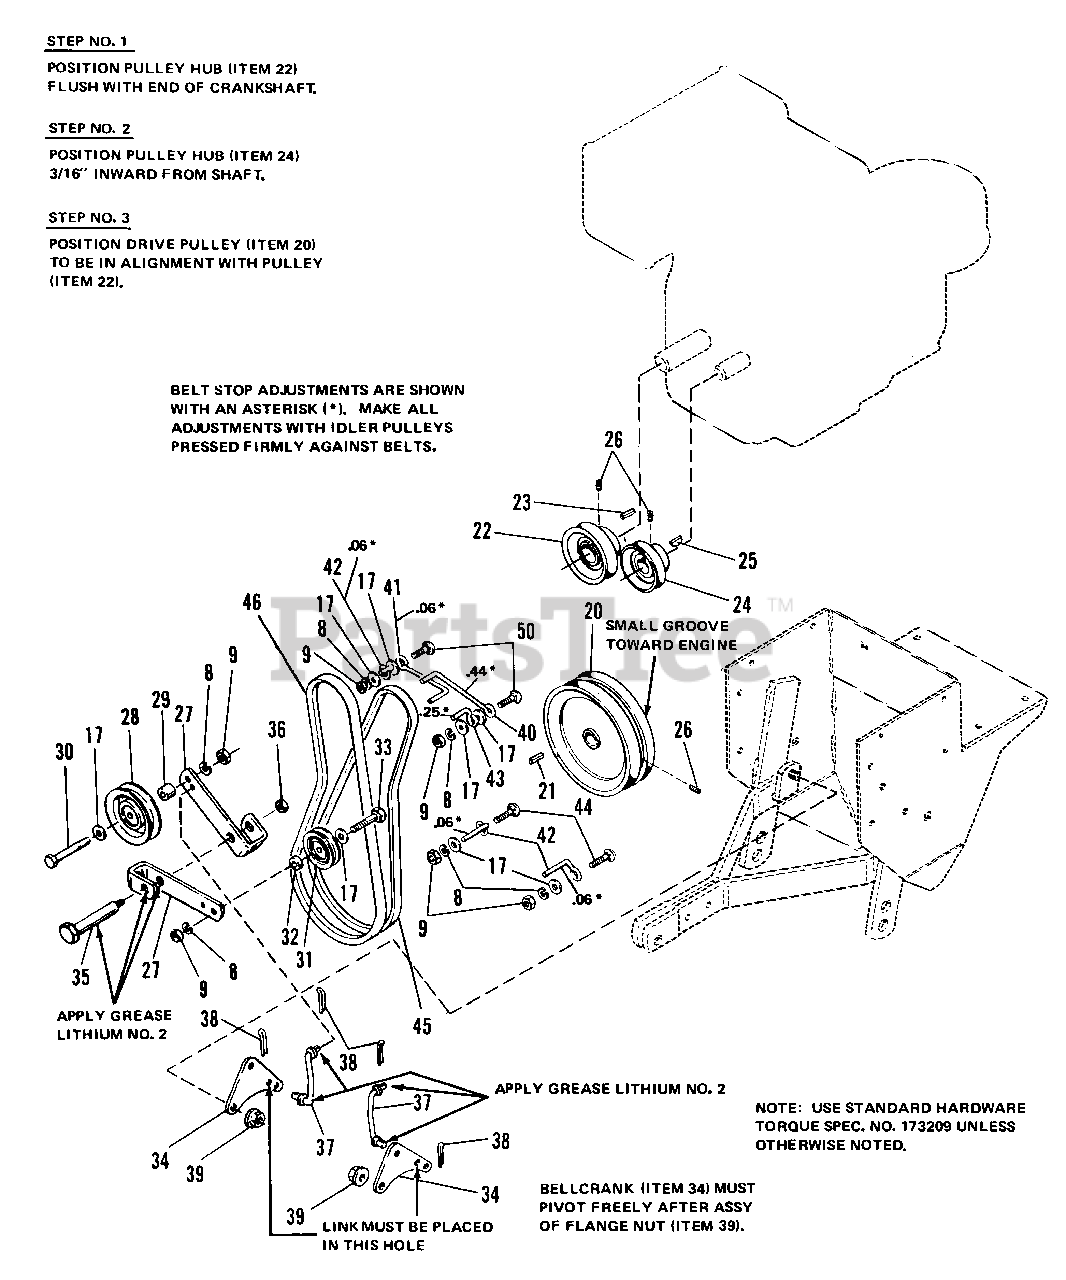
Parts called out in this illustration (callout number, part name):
1	FRAME ASSY
2	WHEEL & TIRE ASSY
3	BOLT, Shoulder
4	LOCKWASHER, Spring, 1/2
5	NUT, Hex, 1/2-13
6	STOP, Plate
7	CAPSCREW, Hex Hd., 3/8-16 x 1-1/2
8	LOCKWASHER, Spring, 3/8
9	NUT, Hex, Full, 3/8-16
10	BAR, Depth
13	PIN, Quick, 1-/78
15	CAPSCREW, Hex Hd., 5/16-18 x 1-3/4
16	WASHER, Plain, 3/8
17	WASHER, Plain, 5/16
18	LOCKWASHER, Spring, 5/16
19	NUT, Hex, 5/16-18
20	PULLEY, Drive
22	PULLEY, Forward
24	PULLEY, Engine, Reverse
25	KEY, Woodruff, #6, 5/32 x 5/8
26	SETSCREW, Hex Skt., Cup Pt., 5/16-18 x 5/16
27	LEVER, Idler Pulley
28	PULLEY, Idler
30	CAPSCREW, Hex Hd., 3/8-16 x 1-3/4
31	PULLEY, Idler
33	CAPSCREW, Hex Hd., 3/8-16 x 1-1/2
34	BELLCRANK
35	BOLT, Pivot
36	NUT, Hex, Full Lock, 5/16-18
37	ROD, Link
38	PIN, Cotter, 1/16 x 3/4
39	NUT, Hex Lock, Flange, 5/16-18
40	STOP, Belt
42	STOP, Belt
43	STOP, Belt
44	BOLT, Rd. Hd., Sq. Nk., 3/8-16 x 1
45	BELT, V (Reverse)
46	BELT, V (Forward)
48	SCREW, Hex, Wshr Hd., Taptite, 1/4-20 x 3/8
50	BOLT, Rd. Hd., Sq. Nk., 3/8-16 x 1-1/4
51	DECAL, 1008
52	DECAL, Roticul, R.H.
53	DECAL. Roticul. L.H.
